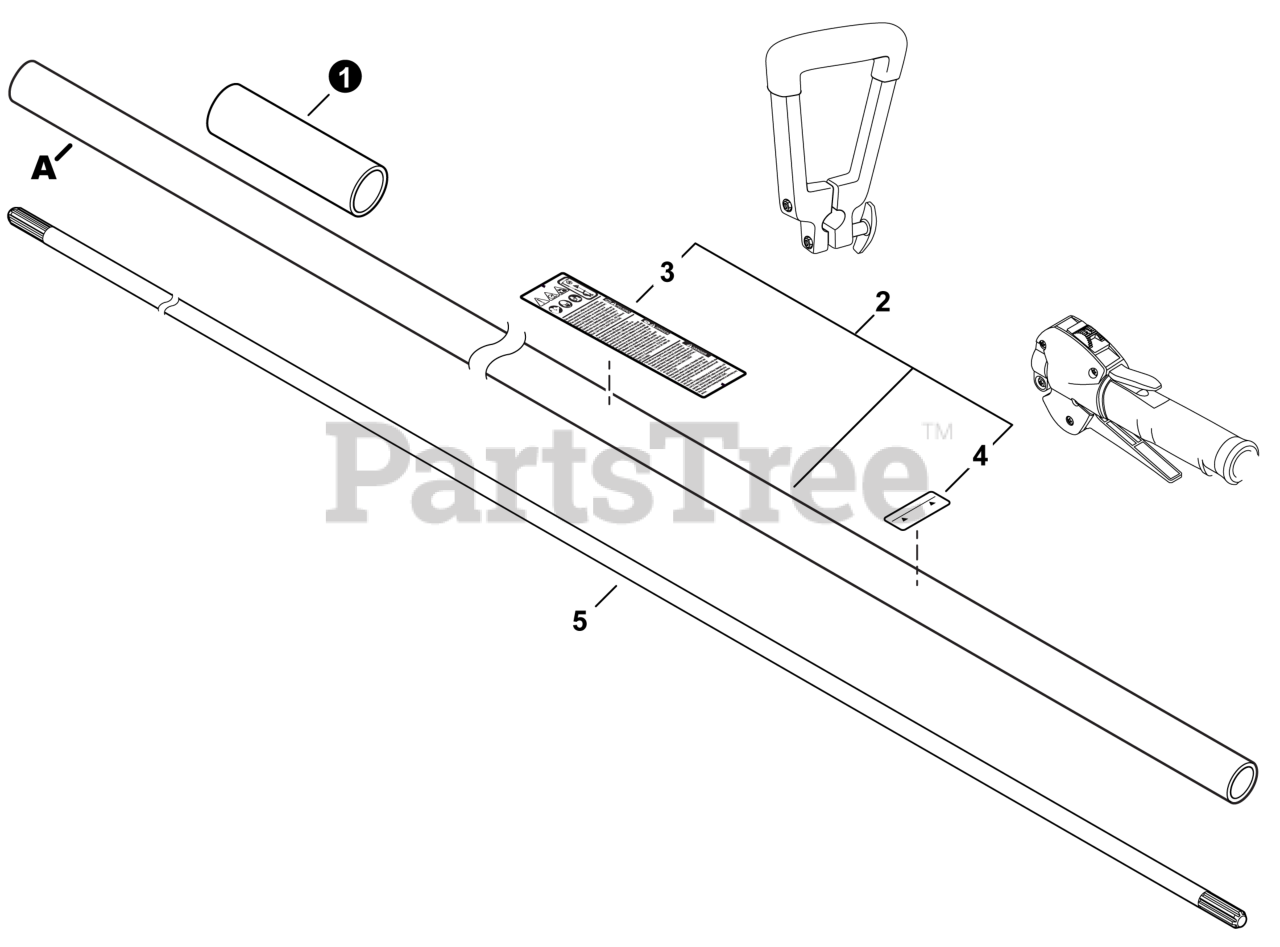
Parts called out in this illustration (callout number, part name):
1	PROTECTOR, MAIN PIPE 25 MM
2	MAIN PIPE ASSY
3	LABEL - CAUTION
4	LABEL - ALIGNMENT
5	DRIVESHAFT
